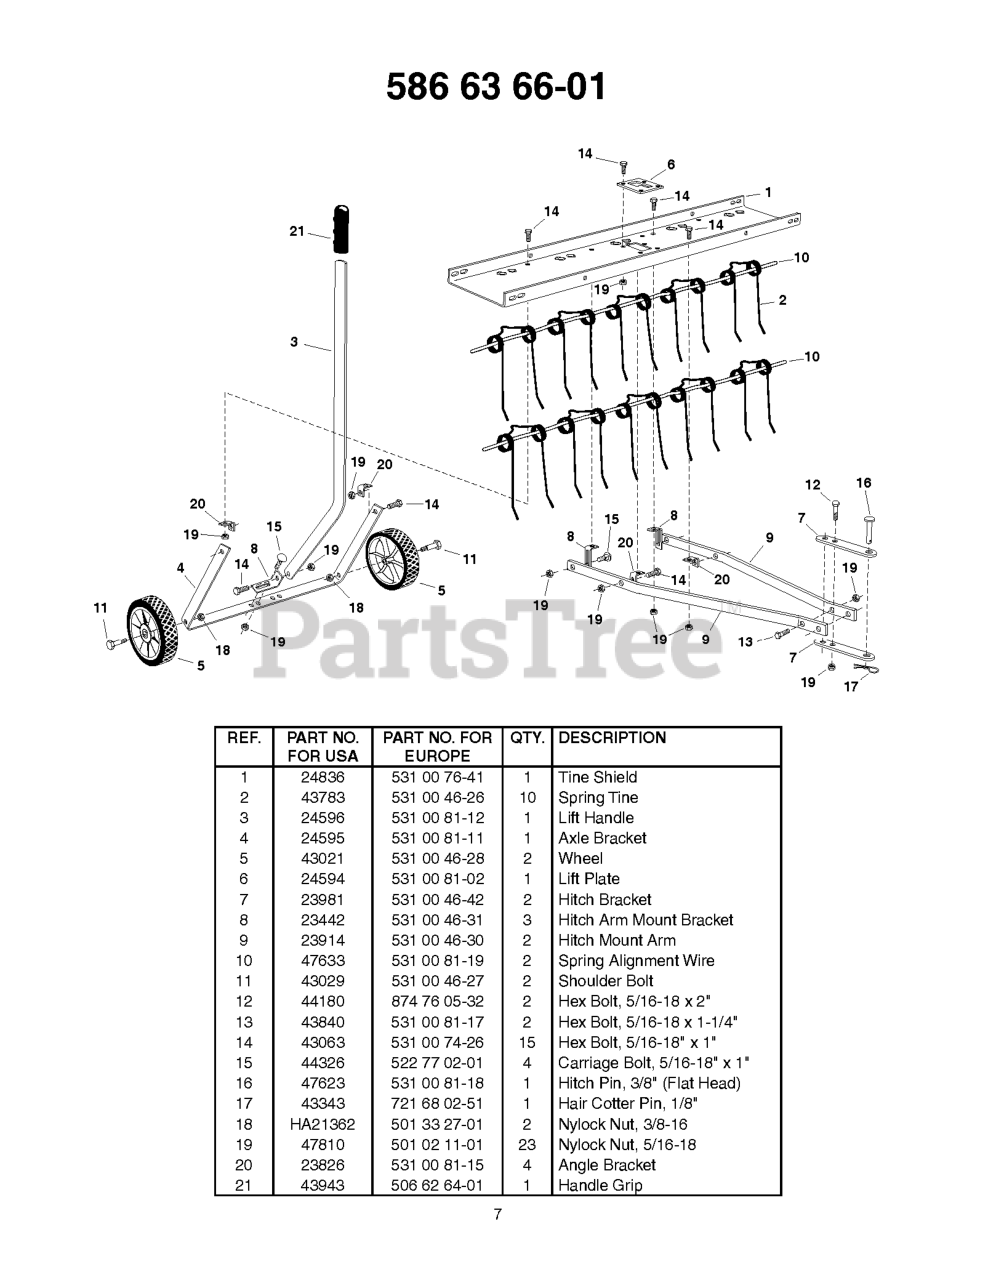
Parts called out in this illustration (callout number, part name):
2	SPRING TINE
7	BRACKET THATCHER
12	Bolt Fin Hex 5/16 - 18 Unc x 2 Gr. 2
21	Rubber Grip
